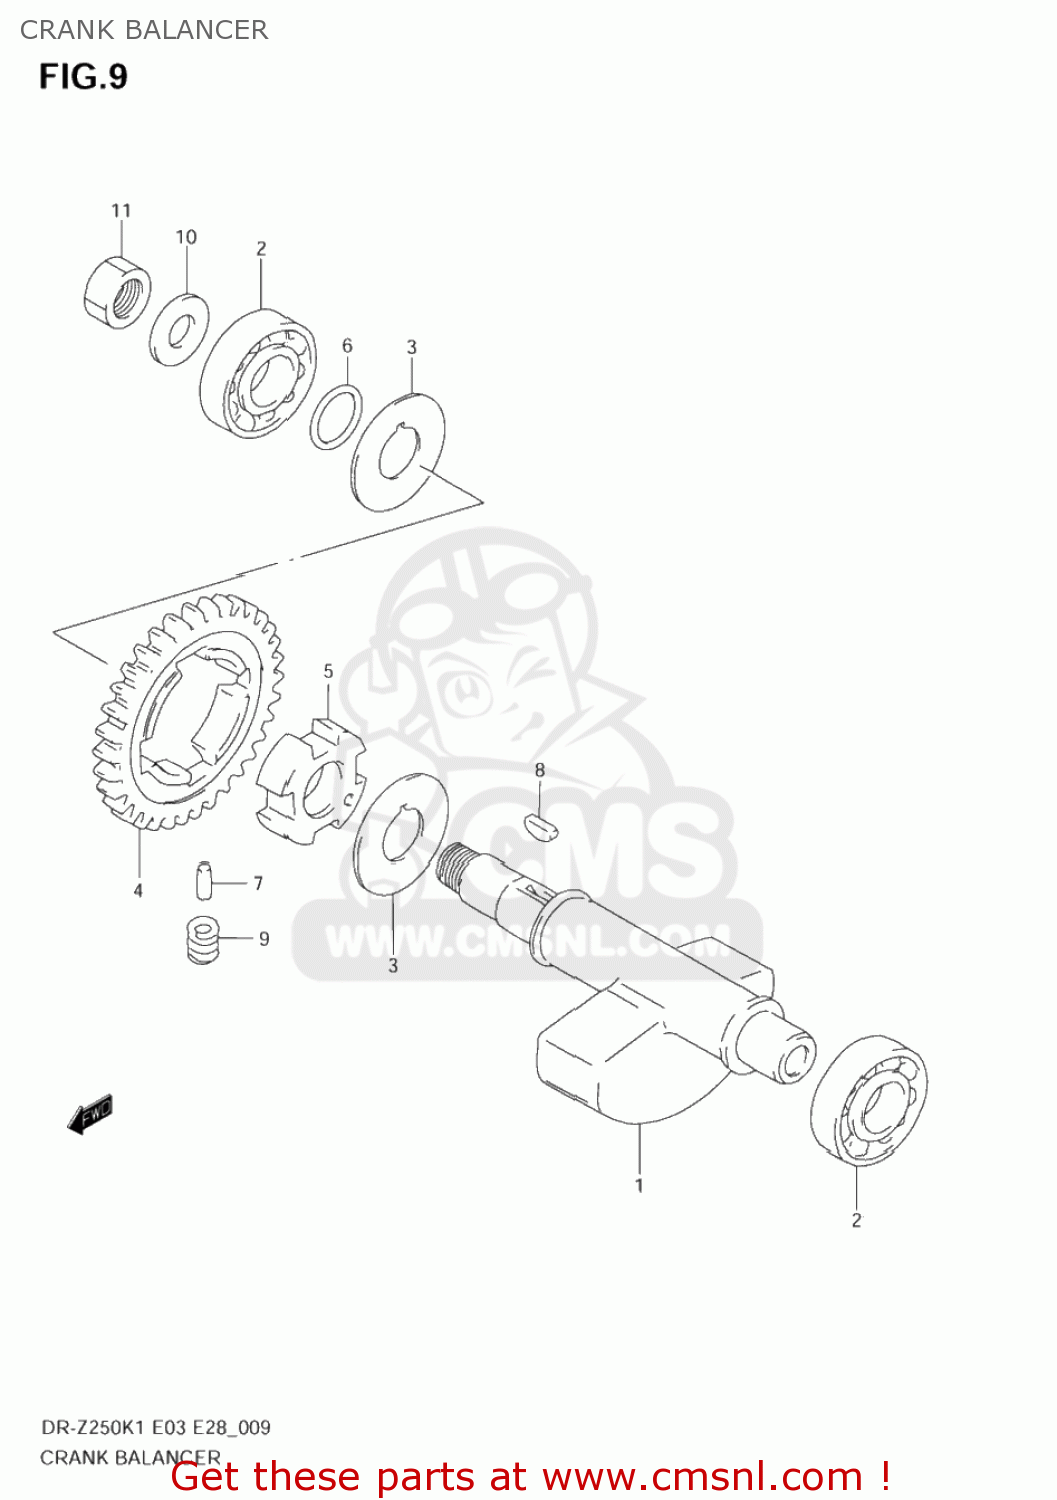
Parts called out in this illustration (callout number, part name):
1	BALANCER,CRANK
2	BEARING(15X42X13)
3	WASHER
4	GEAR,CRANK BAL DRIVEN(NT:34)
5	RACE,CRK BAL DRIVEN GR INNER
6	SHIM(16X22X0.5)
7	PIN(4.5X9.5)
8	KEY
9	SPRING
10	WASHER
11	NUT
